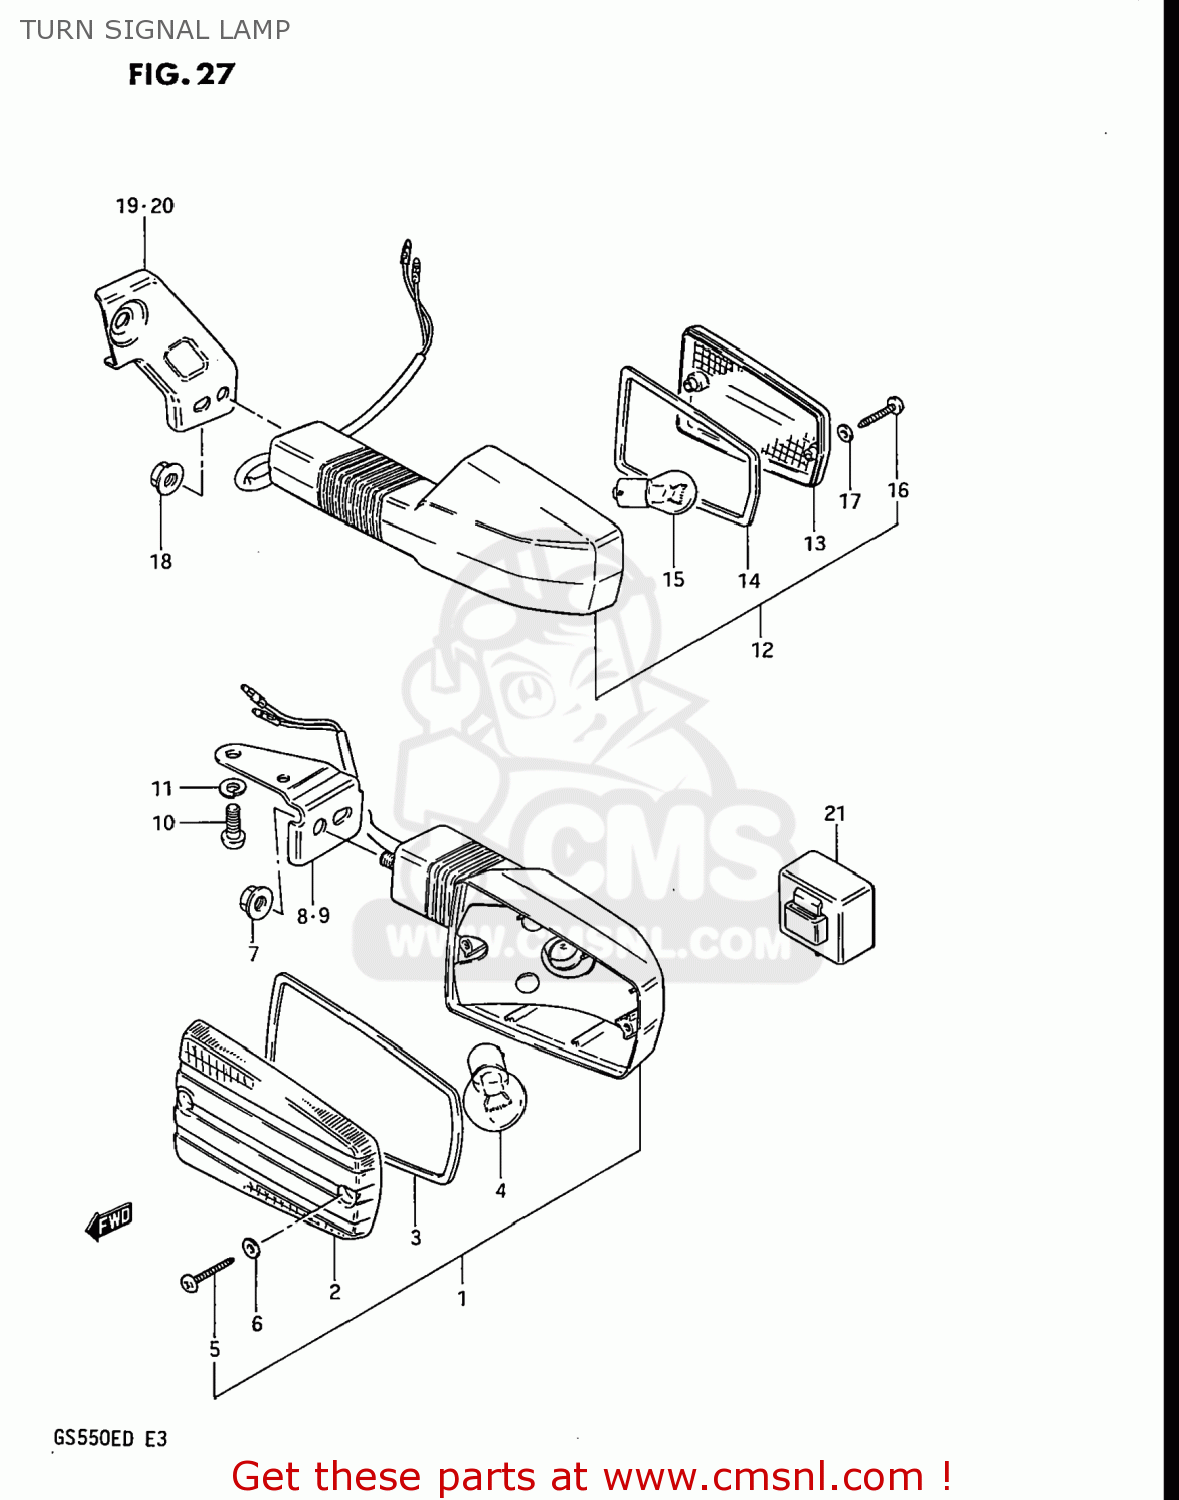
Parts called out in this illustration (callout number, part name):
1	LAMP ASSEMBLY,FRONT TURN SIGNAL
2	LENS
3	GASKET (NAS)
4	BULB(12V23W,STANLEY,A4577A)
5	SCREW
6	GASKET (NAS)
7	NUT M8
8	BRACKET,FRONT TURN SIGNAL
9	BRACKET,FRONT TURN SIGNAL
10	SCREW
11	LOCK WASHER
12	LAMP ASSEMBLY,FRONT TURN SIGNAL
13	LENS
14	GASKET (NAS)
15	BULB(12V23W,STANLEY,A4577A)
16	SCREW
17	GASKET (NAS)
18	NUT
19	BRACKET,REAR TURN SIGNAL
20	BRACKET,REAR TURN SIGNAL
21	RELAY,TURN SIGNAL
